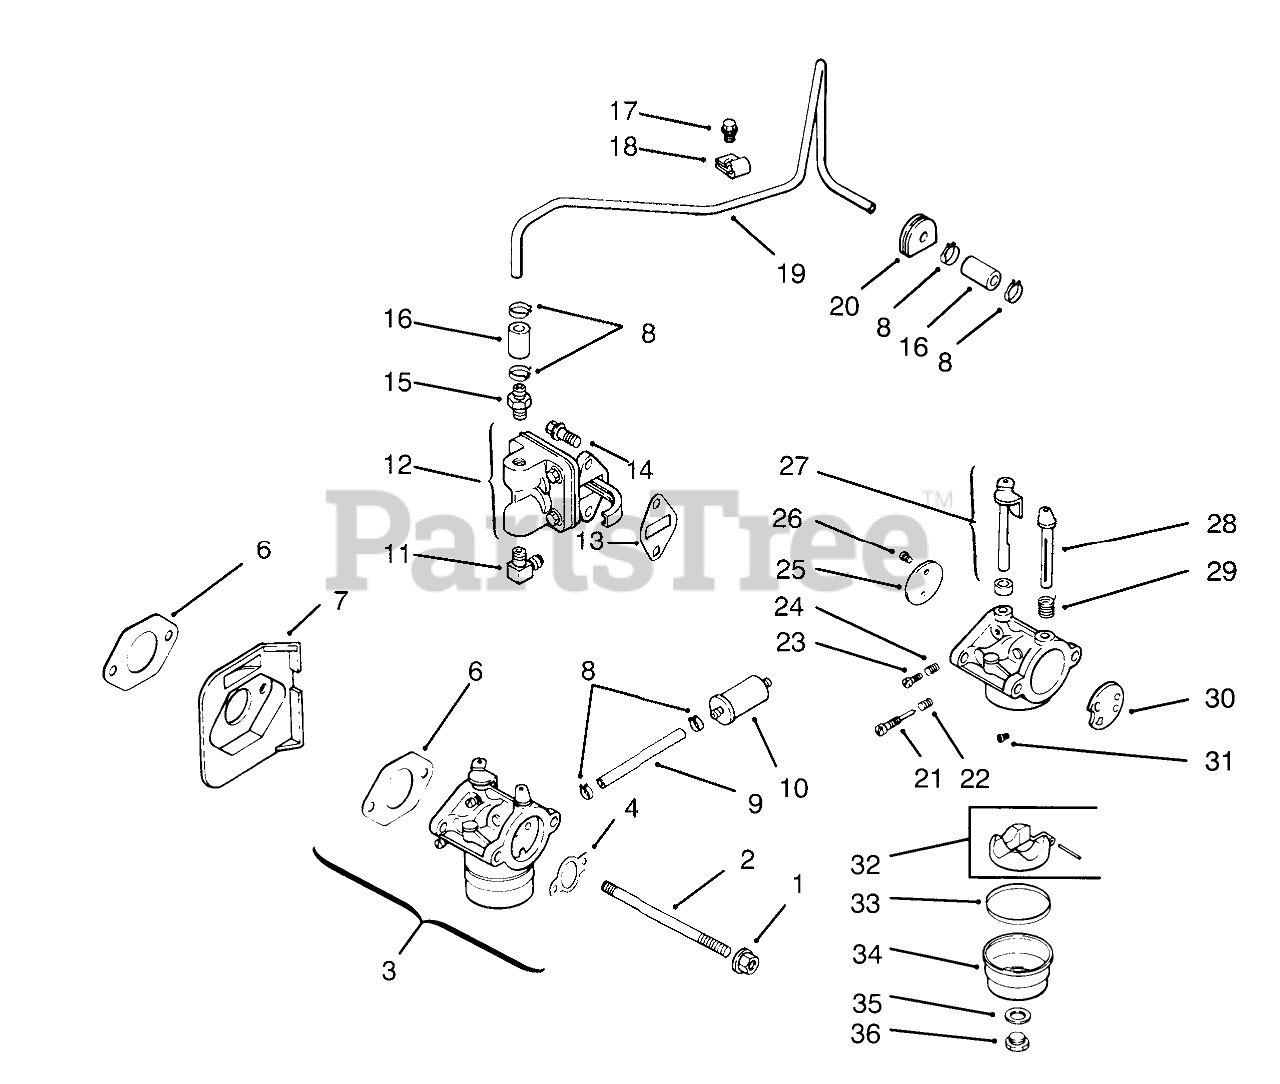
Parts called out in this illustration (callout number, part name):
1	Nut M6x1.0 (Only On: 72042,72043,72062,72063)
2	Stud M6x1.0x110 (Only On: 72042,72043,72062,72063)
3	Kit-Carb INCL 4/6/21 -36 (Only On: 72042,72043,72062,72063)
4	Gasket-Air Cleaner (Only On: 72042,72043,72062,72063)
6	Gasket-Carburetor (Only On: 72042,72043,72062,72063)
7	Deflector-Heat (Only On: 72042,72043,72062,72063)
8	Clamp-Hose (Only On: 72042,72043,72062,72063)
9	Line-Fuel 3" (Only On: 72042,72043,72062,72063)
10	Filter-Fuel (Only On: 72042,72043,72062,72063)
11	Connector-90 DEG (Only On: 72042,72043,72062,72063)
12	Kit-Pump INCL 13-14 (Only On: 72042,72043,72062,72063)
13	Gasket-Fuel Pump (Only On: 72042,72043,72062,72063)
14	Screw M6x1.0x20 (Only On: 72042,72043,72062,72063)
15	Connector-Straight (Only On: 72042,72043,72062,72063)
16	Line-Fuel 1.25 Inch (Only On: 72042,72043,72062,72063)
17	Screw M5x0.8x10 (Only On: 72042,72043,72062,72063)
18	Clamp-Fuel Line (Only On: 72042,72043,72062,72063)
19	Line-Fuel (Only On: 72042,72043,72062,72063)
20	Grommet (Only On: 72042,72043,72062,72063)
21	Needle-Idle Fuel Adjust (Only On: 72042,72043,72062,72063)
22	Spring-Idle Fuel (Only On: 72042,72043,72062,72063)
23	Screw-Idle Speed Adjust (Only On: 72042,72043,72062,72063)
24	Spring-Idle Fuel (Only On: 72042,72043,72062,72063)
25	Plate-Throttle (Only On: 72042,72043,72062,72063)
26	Screw-Throttle Plate (Only On: 72042,72043,72062,72063)
27	Shaft-W/Lever & Seal (Only On: 72042,72043,72062,72063)
28	Shaft-Choke (Only On: 72042,72043,72062,72063)
29	Spring-Choke Return (Only On: 72042,72043,72062,72063)
30	Plate-Choke (Only On: 72042,72043,72062,72063)
31	Jet-Main (Only On: 72042,72043,72062,72063)
32	Kit-Float (Only On: 72042,72043,72062,72063)
33	Gasket-Bowl (Only On: 72042,72043,72062,72063)
34	Bowl-Fuel (Only On: 72042,72043,72062,72063)
35	Gasket-Bowl Screw (Only On: 72042,72043,72062,72063)
36	Screw-Fuel Bowl (Only On: 72042,72043,72062,72063)
